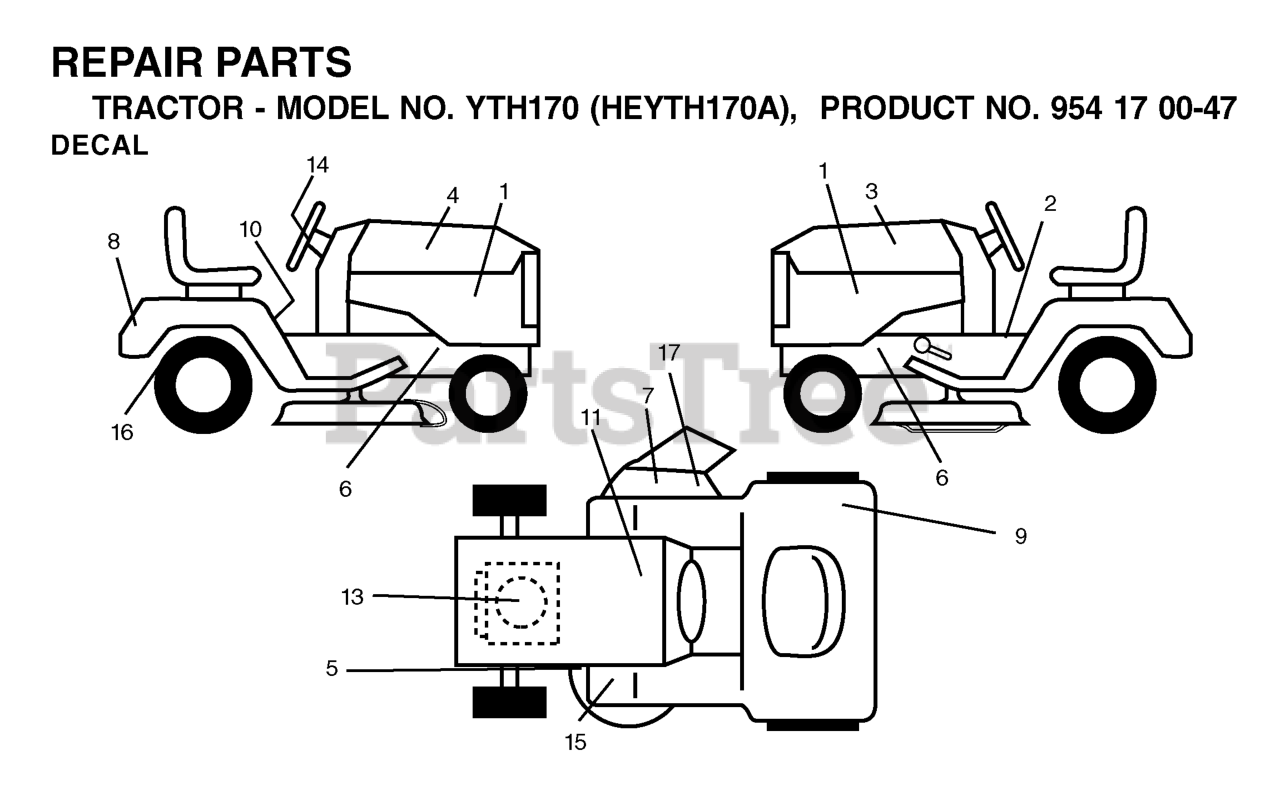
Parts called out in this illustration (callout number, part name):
1	DECAL PNL SIDE
2	DECAL PARK BRAKE
5	DECAL V BELT SCHEMATIC
7	DECAL.INTERNATIONL.CUTFINGER
8	DECAL FENDER HUSQ
9	Decal, Fender 100 DB/CE
10	DECAL READ OWNER'S MAN SYMS
11	DECAL BTRY SYMBOLS
14	DECAL.WHEEL.STEERING.HUSQ.PERM
15	DECAL
16	DECAL
17	DECAL DECK "B" 42"
